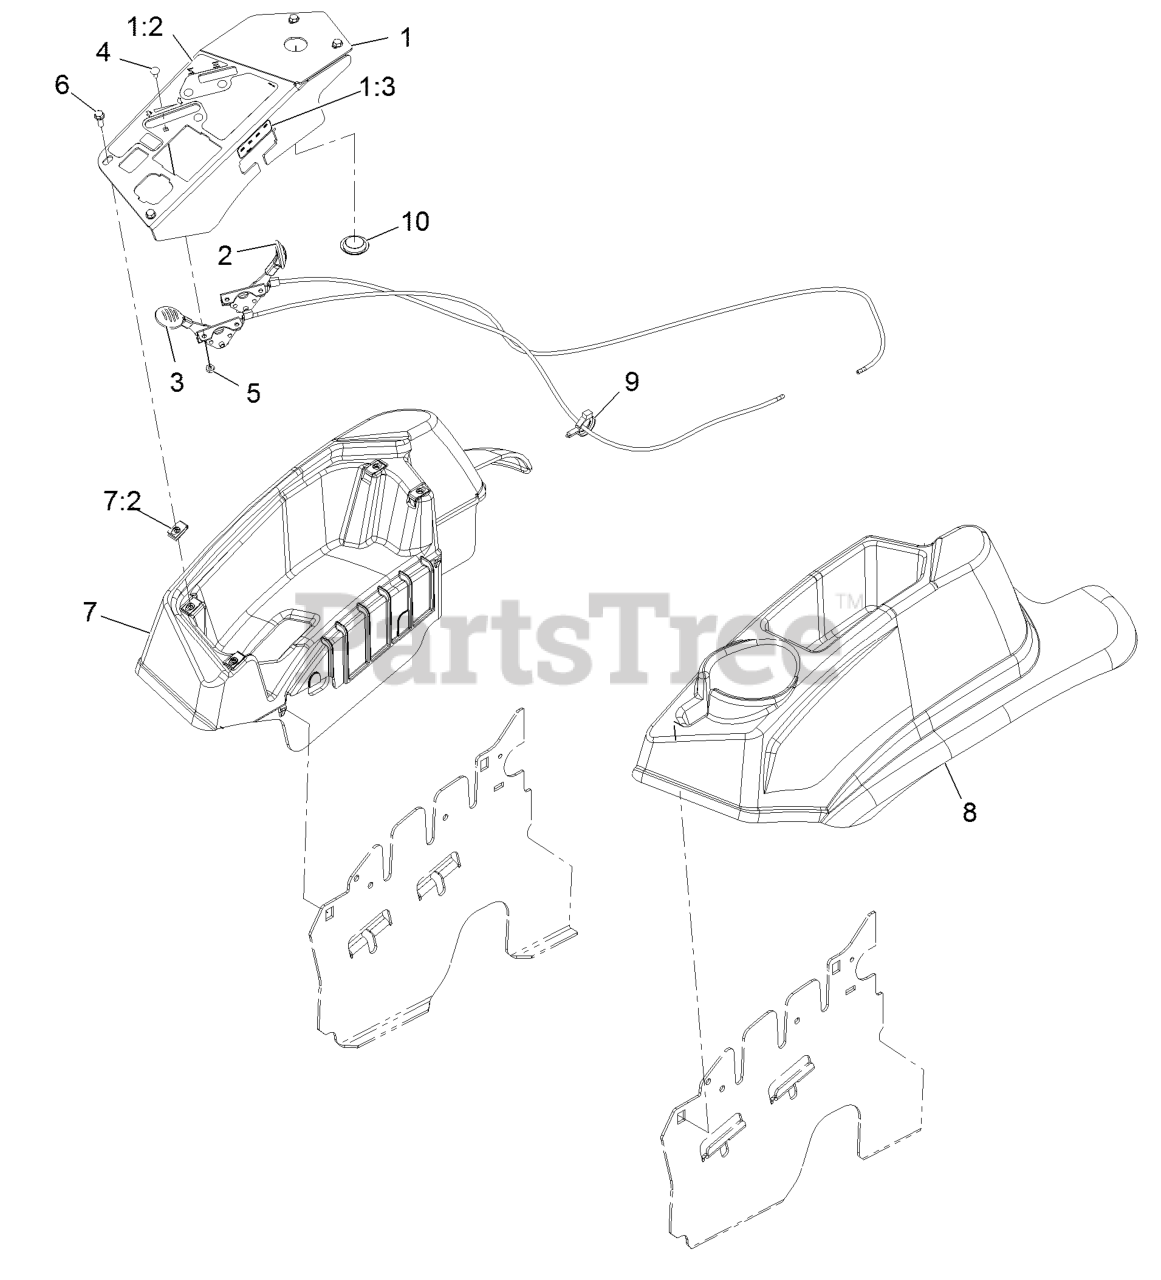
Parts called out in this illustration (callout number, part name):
1	CONSOLE,PANEL W/DECAL
1:2	DECAL-CONTROL PANEL
1:3	DECAL-FUSE
2	ASM, CHOKE CABLE
3	ASM,THROTTLE CABLE
4	BOLT-CARR
5	NUT-LOCK, NI
6	SCREW-HWH
7	CONSOLE,RH AS ASM
7:2	Nut-Retainer-Panel 1/4-20
8	CONSOLE, LH AS
9	CLAMP-HOSE
10	PLUG-PLASTIC
